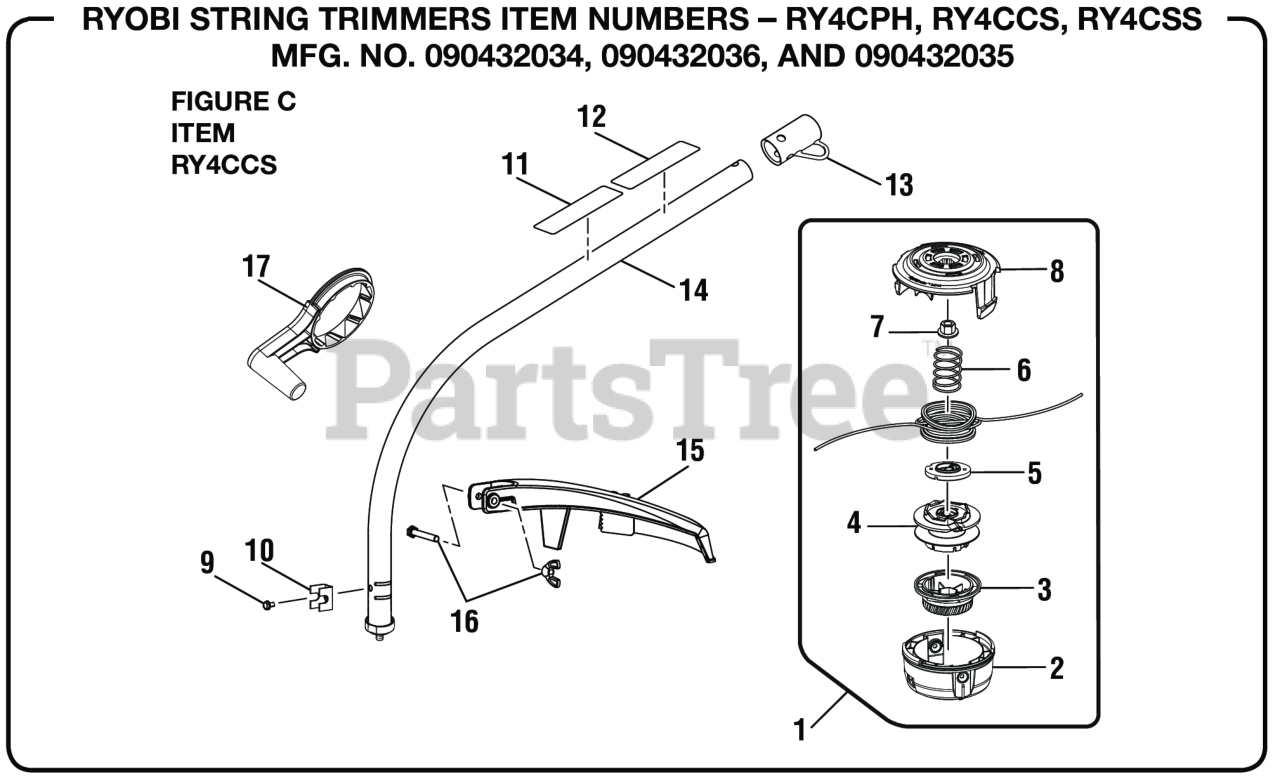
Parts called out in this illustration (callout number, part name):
1	Trimmer Head Assembly (.095)
2	Lower Housing
3	Bump Knob (Green)
4	Spool Assembly
5	String Guide
6	Compression Spring
7	Flange Nut (M8)
8	Upper Housing
9	Screw (#10-32 x 3/8 in., Hex Washer Hd. S.T.)
11	Ryobi EXPAND-IT Label
12	Warning Icon Label
13	Storage Hanger Cap
14	Curved Shaft Assembly
15	Grass Deflector Assembly
16	Fastener Parts Kit
17	Crank Handle Assembly
